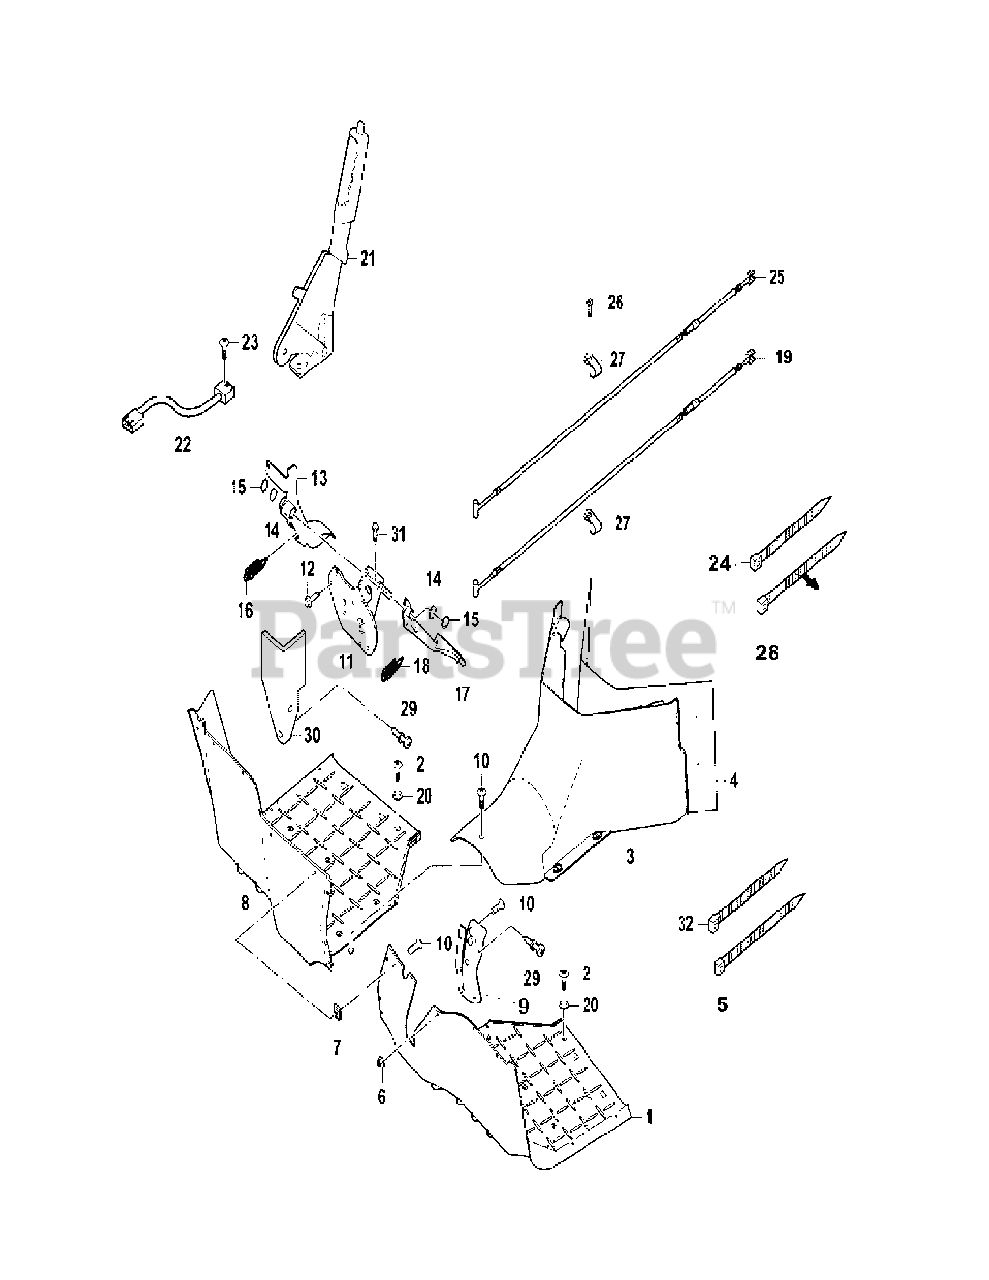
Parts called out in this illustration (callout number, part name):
1	Left Footrest Protector
2	Cross small plate head screw M5×16
3	Axle Cover
4	Insulation Paper III
5	Binding Tape II L=250
6	Hexagon Flange Self-Lock Nuts M6
7	Nut Clip M6
8	Right Footrest Protector
9	Dustproof Plate, Brake Pedal
10	Cross large plate head screw M6×16
11	Rear Brake Pump Bracket Assy
12	Hexagon Flange Bolt M8×20
13	Accelerator Pedal Assy
14	Washer15×22×1.5
15	Washer12×1
16	Tension Spring VI
17	Welding Joint, Parking Pedal
18	Tension Spring VII
19	Throttle Cable (Carburetor Engine)
20	Washer 5×10×1.0
21	Parking System
22	Parking Sensor
23	Screw M4×12
24	Clamp III (L=300)
25	Parking Brake Cable
26	Hexagon Flange Bolt M6×16
27	Clip For Cable
29	Expansion Bolt(Plastic)
30	Mudguard For Brake Pump
31	Hexagon Flange Bolt M8×20
32	Clamp IV (L=370)
